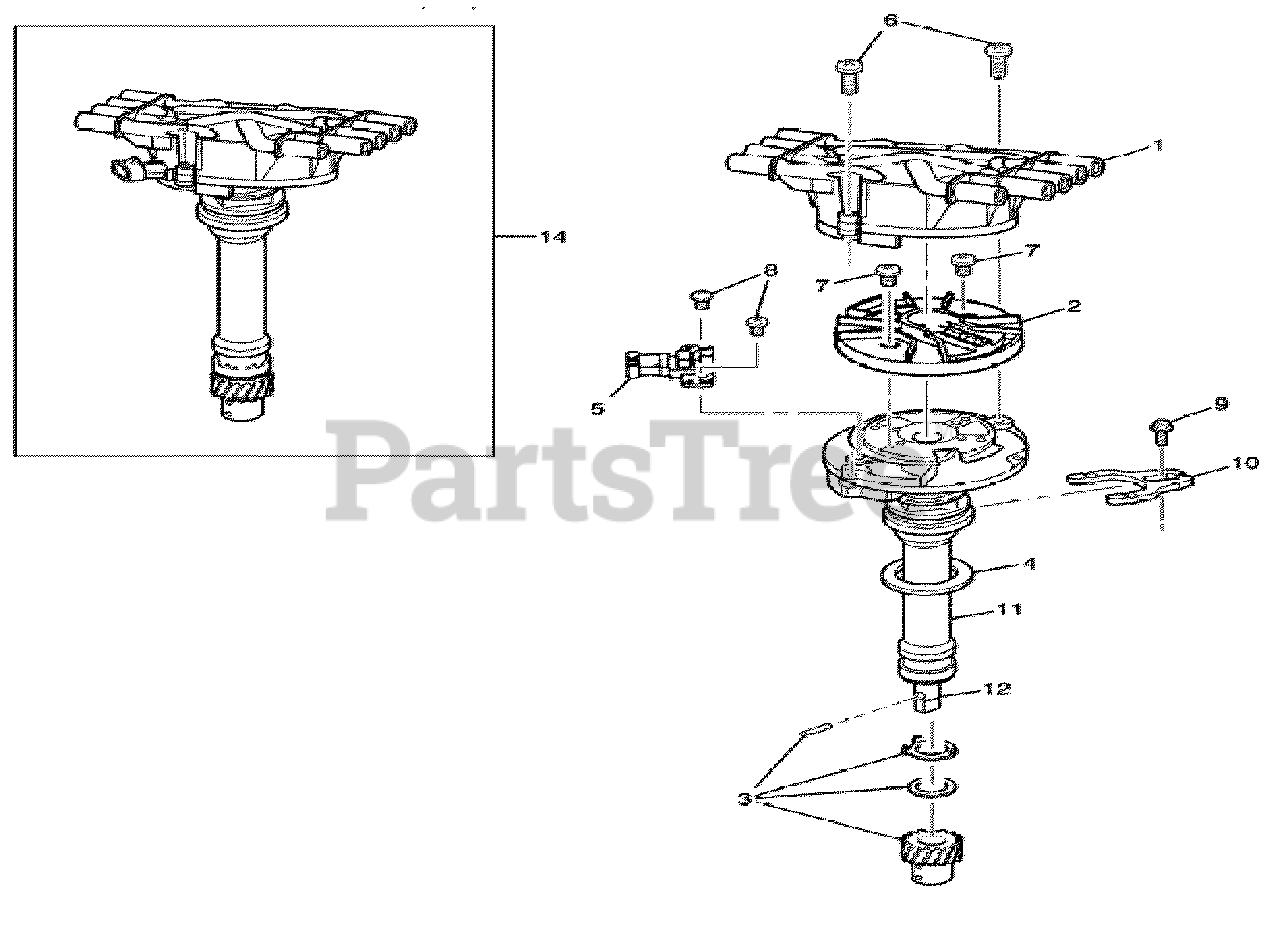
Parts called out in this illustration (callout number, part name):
2	ROTOR
3	* GEAR
4	* GASKET
6	* BOLT
7	* BOLT
8	* BOLT
9	* BOLT
10	* CLAMP
11	* HOUSING
12	* SHAFT
